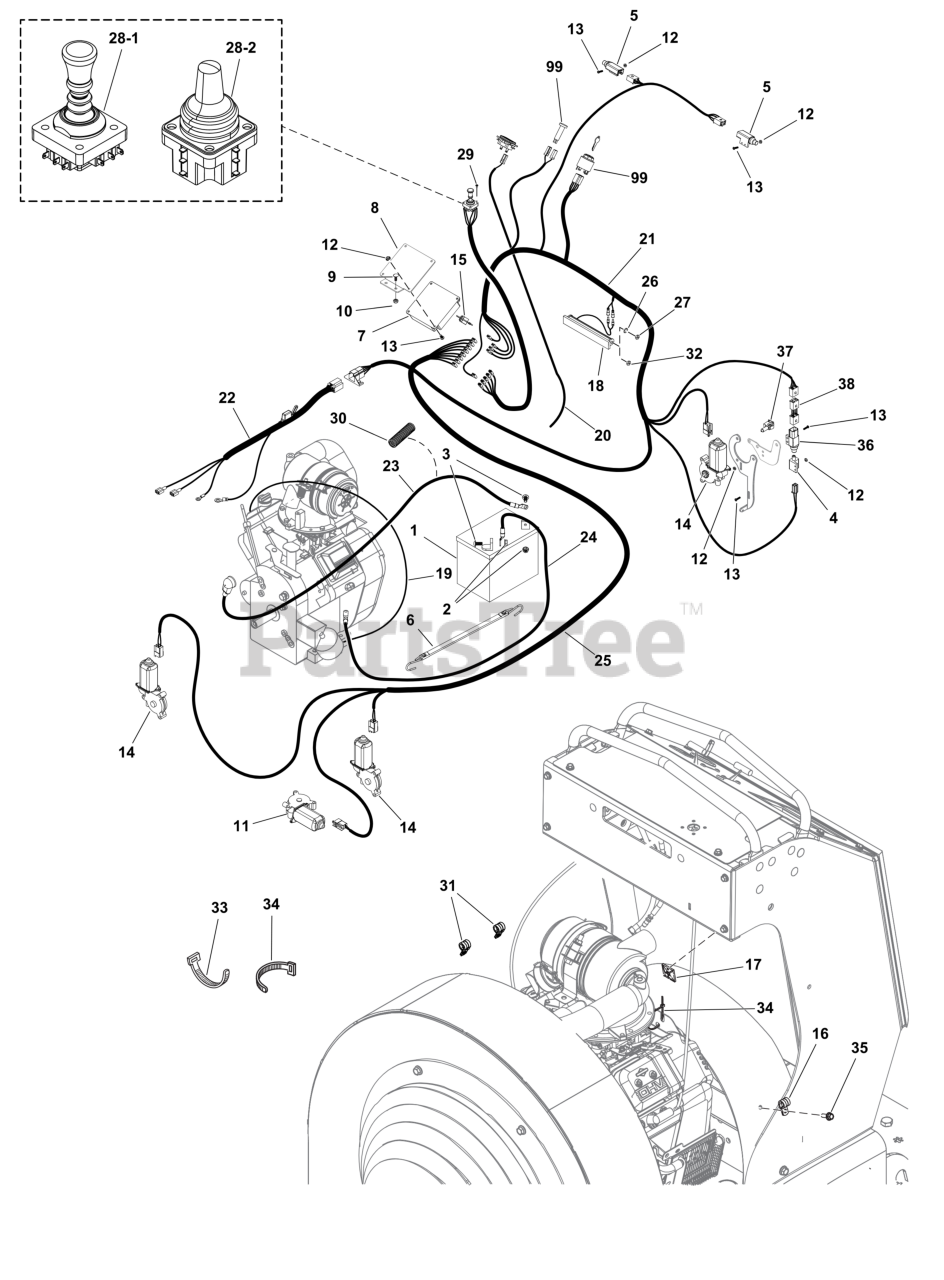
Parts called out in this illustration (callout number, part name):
1	BATTERY
2	NUT, 5/16-18 HEX SERR
3	SCREW, 5/16-18
4	SWITCH, PLUNGER, N.C.
6	STRAP, Battery
7	KIT, RELAY, CONTROL MODULE
9	BOLT, 1/4-20X.750, SQ
12	NUT-HEX & WASHER ASMY
13	SCREW (#10-32 X 3/4, ALLEN, SS)
14	DEFLECTOR, Motor
15	BREAKER, CIRCUIT, 15A
16	CLAMP, VINYL INSULATED, .50
18	HEADLIGHT ASSEMBLY
19	HARNESS, Wiring
20	HARNESS, WIRING
21	HARNESS, Wiring
22	HARNESS, WIRING
23	CABLE, BATTERY, RED
24	CABLE, BATTERY, BLACK
25	HARNESS, WIRING
26	WASHER, 5MM, STAR, CZ
27	NUT, HEX, M5X.8MM, NYLON INSERT
28-1	KIT, JOYSTICK UPDATE
28-2	KIT, Joystick
29	SCREW, #8-32 X 3/8, ALLEN, SS
30	WIRE LOOM, 3/8 ID X 17.5 IN
32	NUT, HEX, M6-1, NYLON INSERT
33	TIE WRAP, 11" Long
34	TIE WRAP, 5-1/2" LONG
38	WIRE HARNESS, JUMPER, BRAKE SWITCH
99	Refer to: Instrument Control Panel Group
